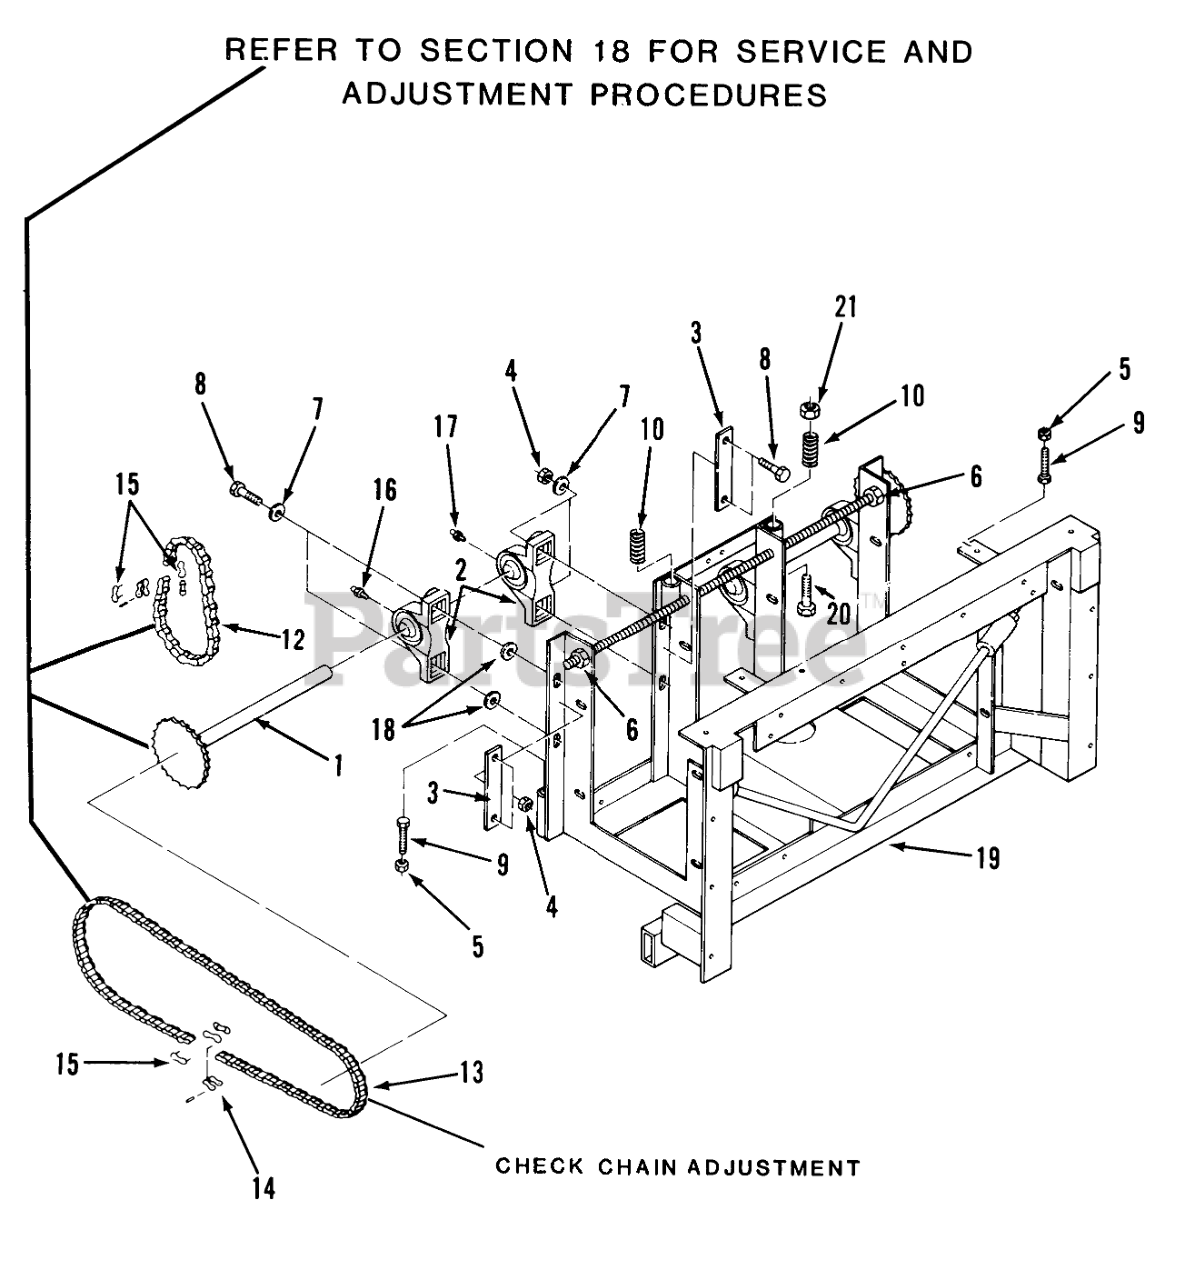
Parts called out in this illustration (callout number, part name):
1	Jackshaft
2	Pillow Block Bearing
3	PLATE PILLOW BLOCK
4	NUT
5	Nut
6	Eslok Nut
7	Washer
8	Bolt
9	Hex Bolt 5/16-18 x 1 1/2
10	Seat Spring
12	Primary Chain
13	CHAIN-#50 SECONDARY
14	HALF LINK
15	Master Link #50
16	Zerk
17	ZERK 90DEGREE
18	Washer
19	Transaxle Frame
20	Bolt 5/16-18 x 2
21	Flanged Nut
